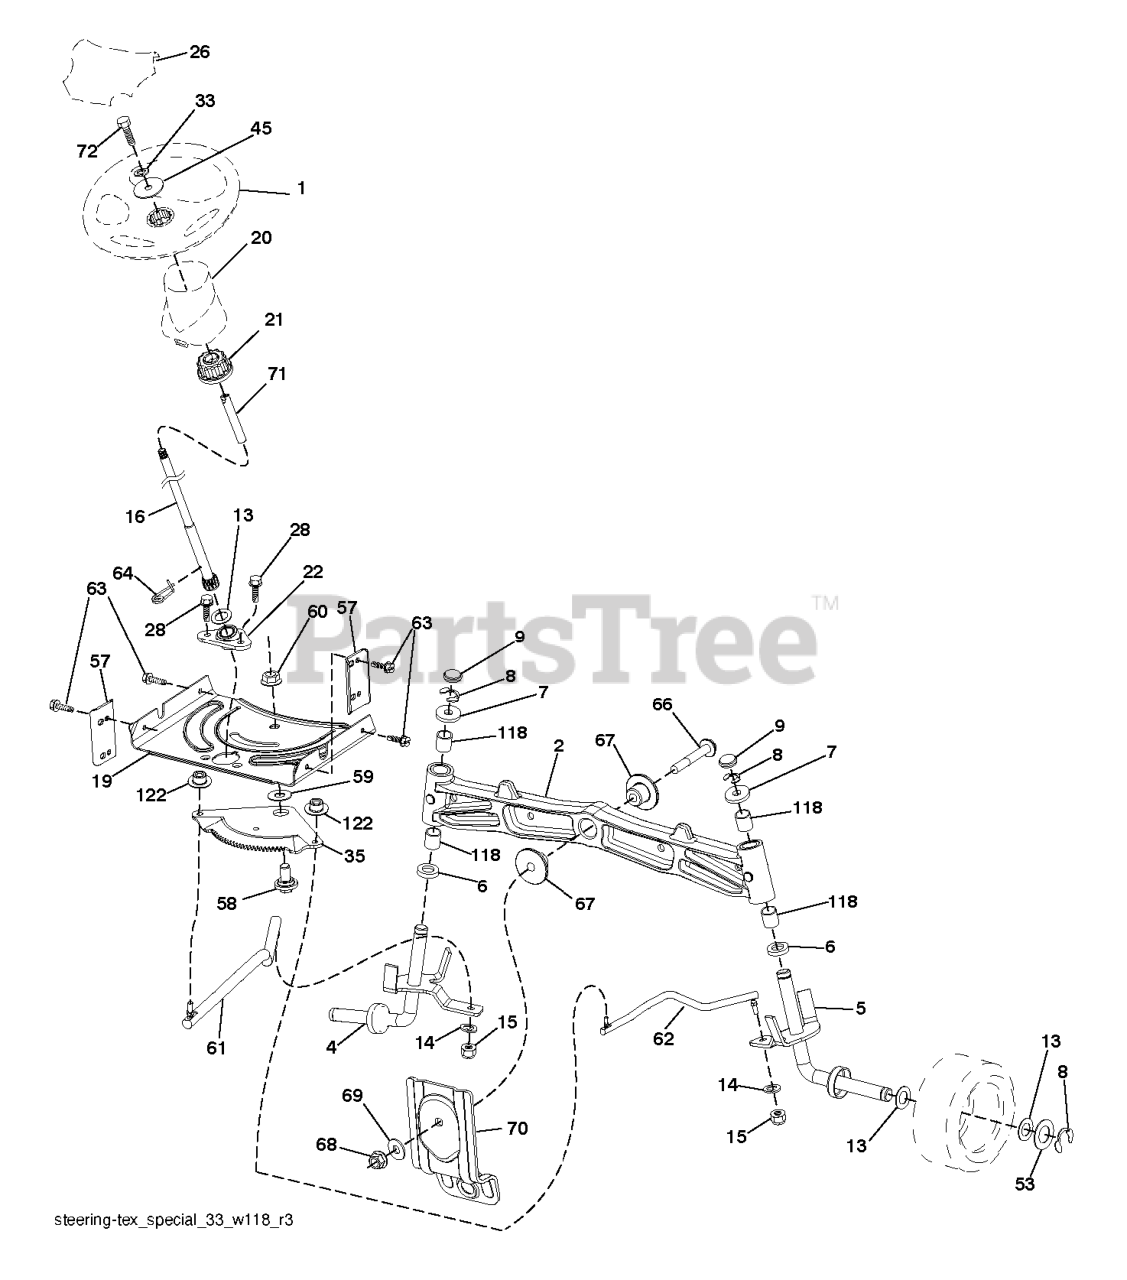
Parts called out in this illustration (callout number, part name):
1	RP WHEEL.STEER.HUSQ.PREM.OVMLD
2	AXLE.SVC.ASM CAST IRON.TEX
4	SPINDLE.WELDED.LH.15"TEX
5	SPINDLE.WELDED.RH.15"T
6	THRUST WASHER
9	CAP.SPINDLE.BLACK
14	WASHER, LOCK 3/8
15	NUT CROWNLOCK 3/8-24
16	SHAFT.STEER.3/4.PLATED.TEX
19	PLATE.STEER.DDL.NLT/NG
20	BOOT, STEERING
21	ADAPTER, WHEEL STNG..
22	STEERING.SUPT.LOWER.
26	RP INSERT.CAP.WHL.STRG.HUSQ.
28	SCREW, 3/8-16X3/4
33	WASHER.LOCK.HVY.HLCL.SPR.5/16
35	GEAR.SECTOR.PLATE.DDL.
45	WASHER.11/32
53	WASHER.HARDENED
57	BRACKET.UPSTOP.TEX
58	BOLT.SHOULDER.SECTOR.P
59	WASHER.THURST.SECTOR.S
60	NUT FLANGE LOCK 5/8-11
61	DRAGLINK.LH.BALLSTUD.D
62	DRAGLINK.RH.BALLSTUD.D
63	SCREW
64	RETAINER.CLIP.SPRING.S
66	BOLT HEX FGHD 7/16-14 X 3 SERR
67	BUSHING.PM.FRONT AXLE
68	NUT.LOCK.FLANGE.7/16
69	WASHER.1.5X.505X.118
70	BRKT.DECK.SUSPENSION.F
71	SHAFT.EXTEN.STRG.SPLINE
72	BOLT 5/16-18 X 4 W/PATCH
118	BUSHING, AXLE CAST
